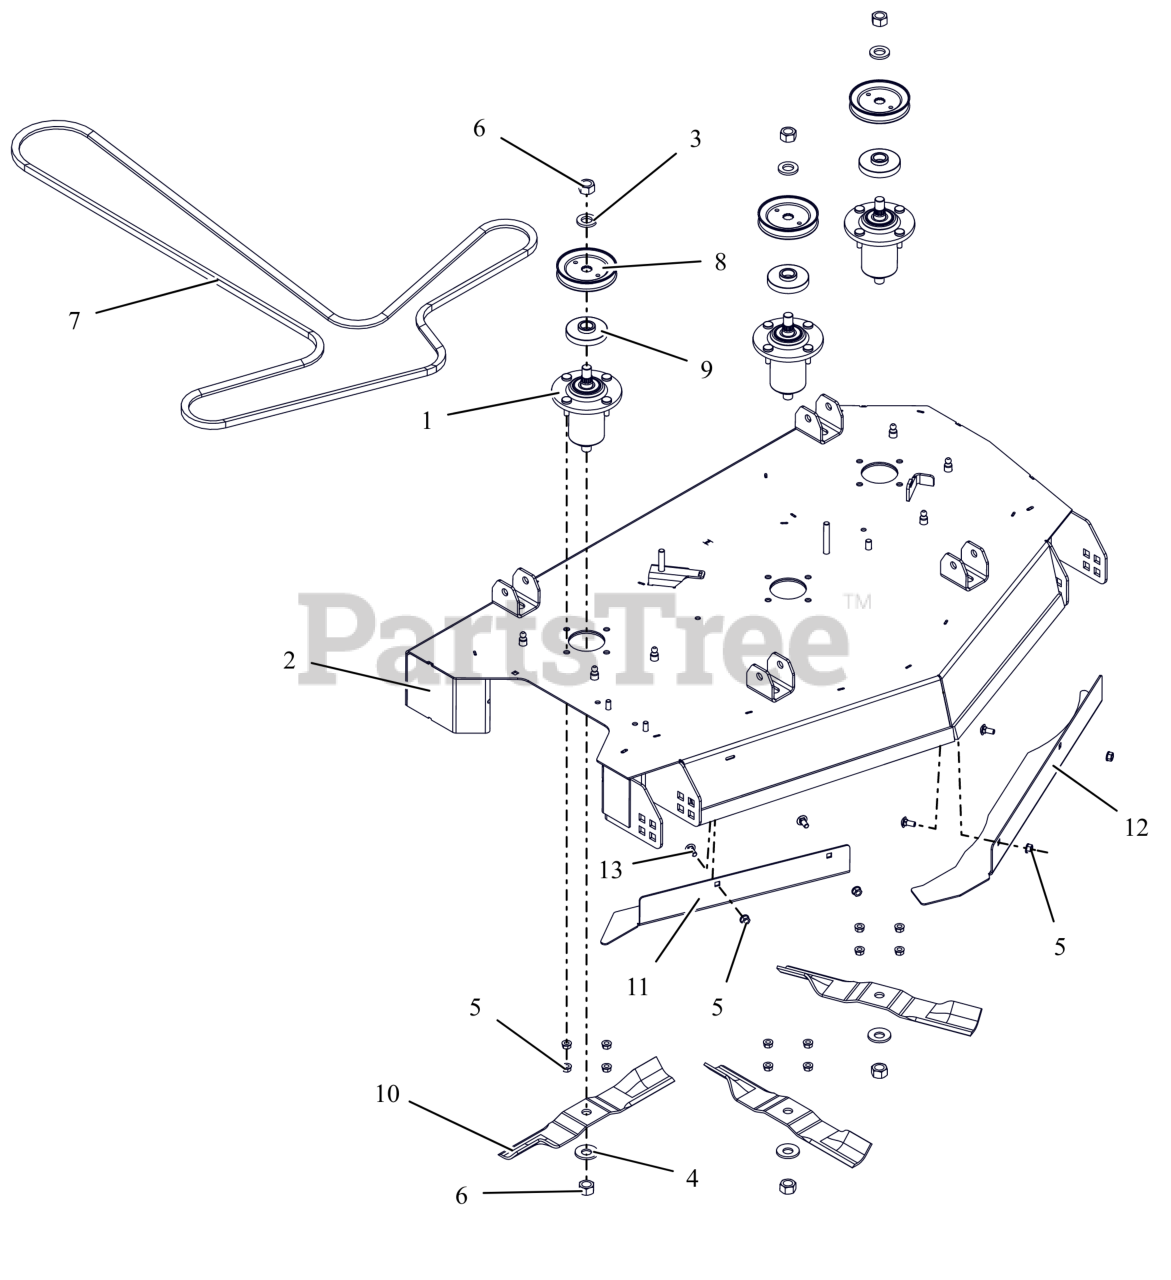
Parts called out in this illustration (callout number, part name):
1	ASM, ALUMINUM SPINDLE SUB
2	KIT-GRAVELY DECK 42" W/ DECALS
3	SPCR- .735 X 1.313 X .165
4	WSHR-BLVL .669X1.535X.138
5	NUT,LK-CTR-FLG .31-18 GF ZCC
6	NUT-STD .625-18 ZCC
7	V-BELT, HA-WRAPPED
8	PULLEY-V-4.00 ODX.625SPLINE ID
9	SHIELD, DUST
10	BLADE- 14.5" MOWER (HI-LIFT)
11	BAFFLE, 42" RH VACUUM (RED)
12	BAFFLE, 42" LH VACUUM (RED)
13	BLT,RHSN .31-18X.75 G5 ZCC
